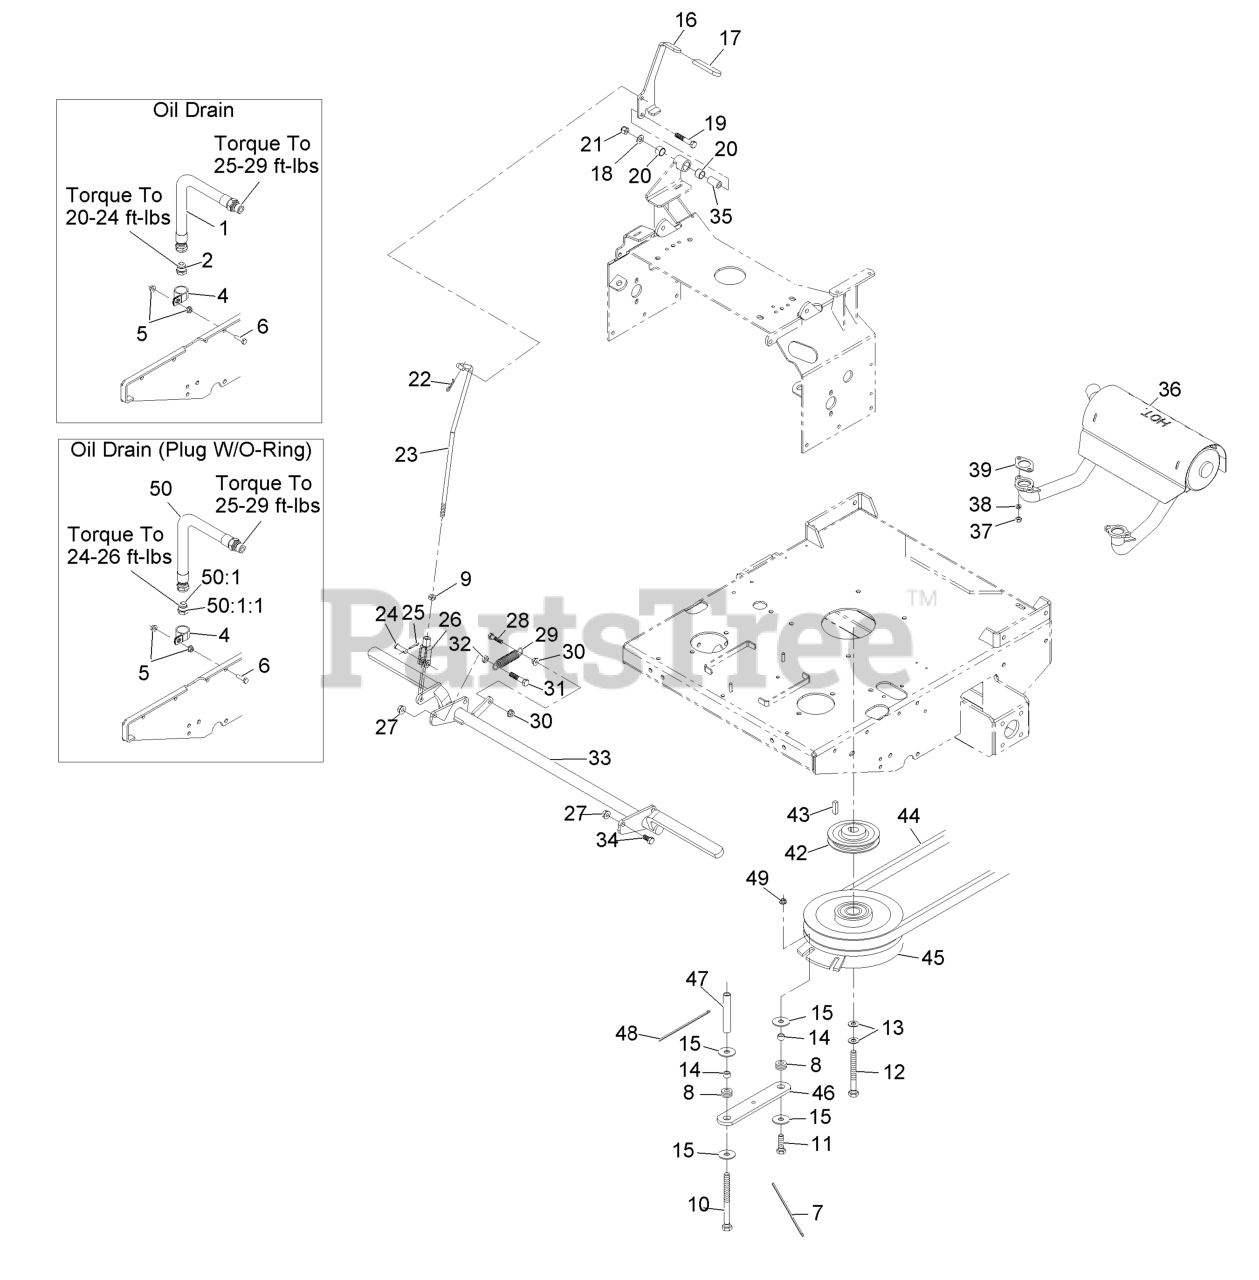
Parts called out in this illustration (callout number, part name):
4	CLIP-LOOM
6	SCREW-HH
7	TIE-PLASTIC
8	GROMMET
9	NUT-HJ
10	SCREW-HH
11	SCREW-HH
12	SCREW-HH
13	WASHER-SPRING
16	LEVER, PARK BRAKE W/DECAL
17	GRIP-LEVER
18	WASHER-FLAT
19	SCREW-HH
20	SLEEVE-BUSHING
21	NUT-LOCK, NI
22	PIN-COTTER
23	LINKAGE, PARK BRAKE
24	PIN-CLEVIS
25	PIN-COTTER
26	YOKE-LINKAGE, BRAKE
27	NUT-HHF, WHIZ
28	SCREW-HH, SPECIAL
29	SPRING-IDLER
31	SCREW-HH
32	NUT-JAM
34	SCREW-HH
35	BUSHING-PIVOT
36	MUFFLER,HORIZONTAL
38	WASHER-LOCK
39	GASKET-EXHAUST
42	PULLEY
44	BELT,B 83.65
44	BELT,DECK DRIVE
45	CLUTCH ASM
46	STRAP-CLUTCH, BRAKE
47	SPACER,SHIELD
48	TIE-CABLE
50	ENGINE OIL DRAIN HOSE ASM
50:1	PLUG-HH
50:1:1	O-RING
